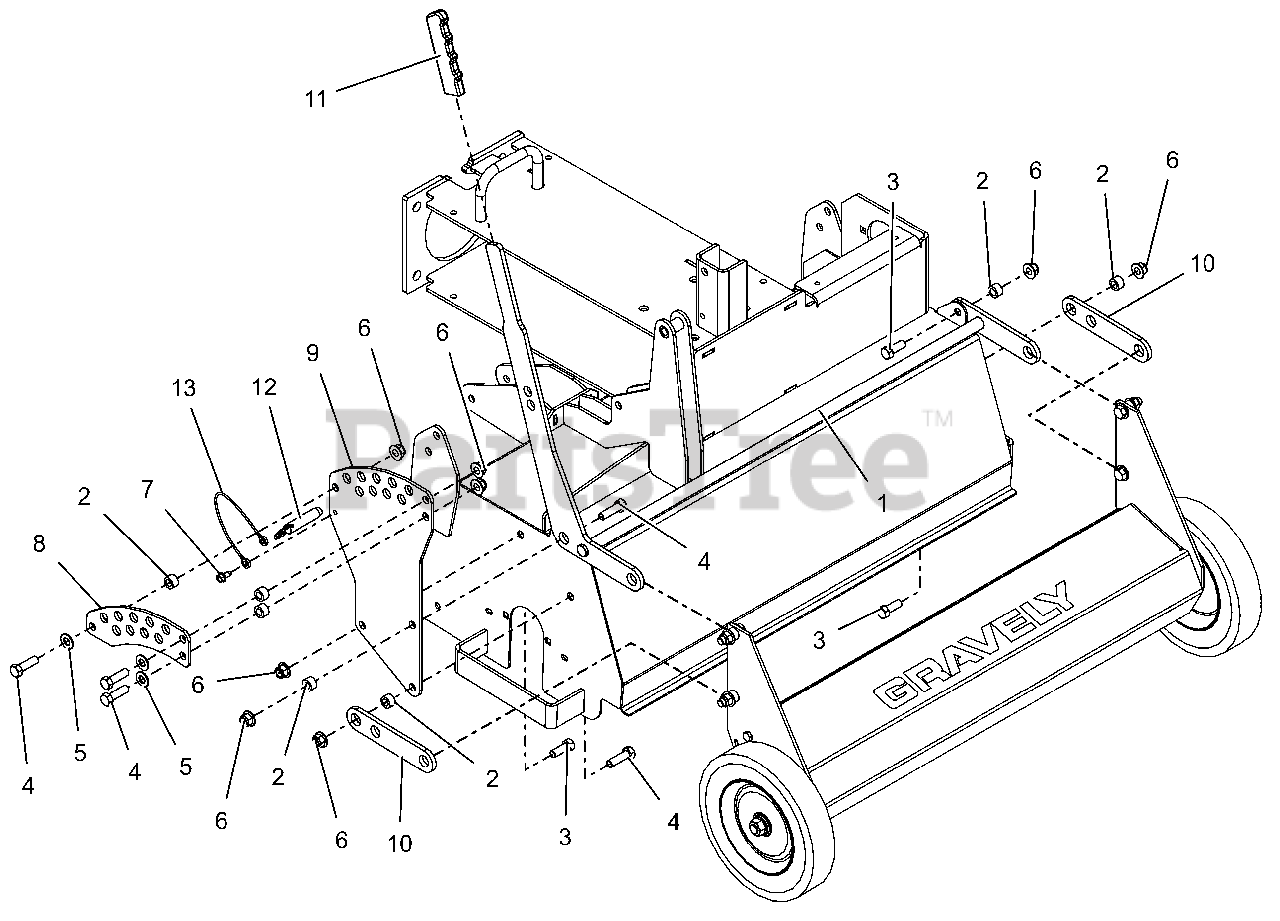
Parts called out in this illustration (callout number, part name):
1	WLDMT, CONTROL HEIGHT
2	BSHG-SLV .377X.624X.370
3	BLT,HEX .38-16X1.00 G5 ZCC
4	BLT, HEX .38-16X1.25 G5 ZCC
5	WSHR,FLT .406X.812X.065 ZCC
6	NUT,NYL-FLG .38-16 GF ZCC
7	SCR-TAP .25-20X.50 HWH ZCC
8	BRKT, CONTROL OUTER (BLACK)
9	BRKT, CONTROL
10	PLT, LINK ST
11	GRIP
12	PIN, .500 x 2.000 USABLE LG BALL
13	CABLE, 12.0 LANYARD, NYLON
